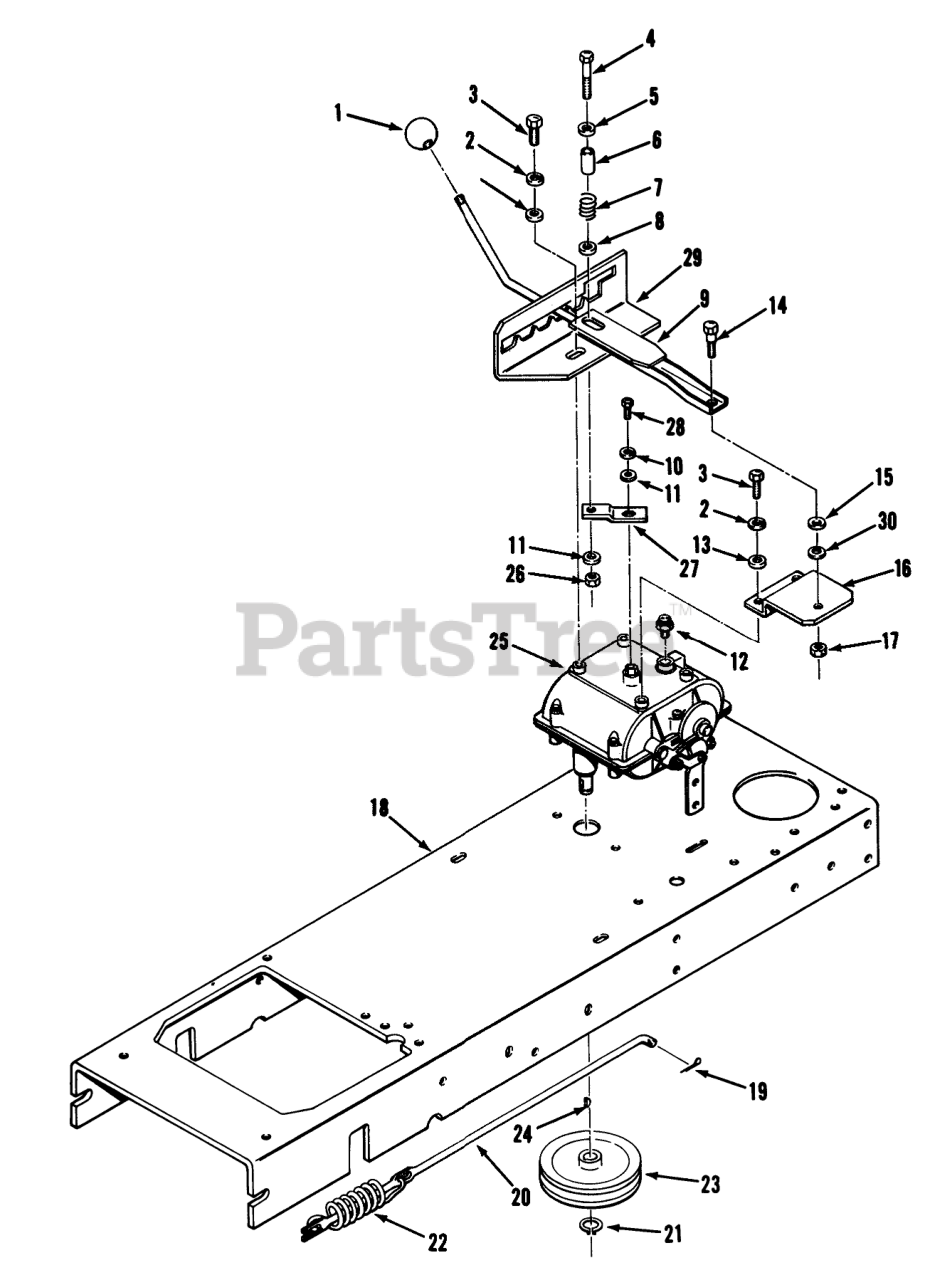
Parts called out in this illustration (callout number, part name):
2	WASHER-LOCK
3	SCREW-HWHTF
4	SCREW-HH
5	WASHER-FLAT
6	SPACER-SPLIT
7	SPRING-COMPRESSION
8	WASHER-FLAT
9	SHIFT LEVER WA B
10	WASHER-LOCK
11	WASHER-FLAT
12	NEUTRAL SWITCH
13	WASHER-PLAIN
14	SCREW-SHOULDER
15	WASHER-BELLEVILLE
16	SHIFT MTG BRKT
17	NUT-LOCK, NI
18	Frame-Main
19	PIN-COTTER
20	BRAKE ROD
21	RING-SNAP, EXTERNAL
22	SPRING-EXT
23	Clutch Rod
24	KEY-WOODRUFF
25	TRANSMISSION
26	NUT-LOCK, CONE
27	LEVER-SHIFT
28	SCREW-HH
29	Gate-Shift
30	SPACER-PIVOT
